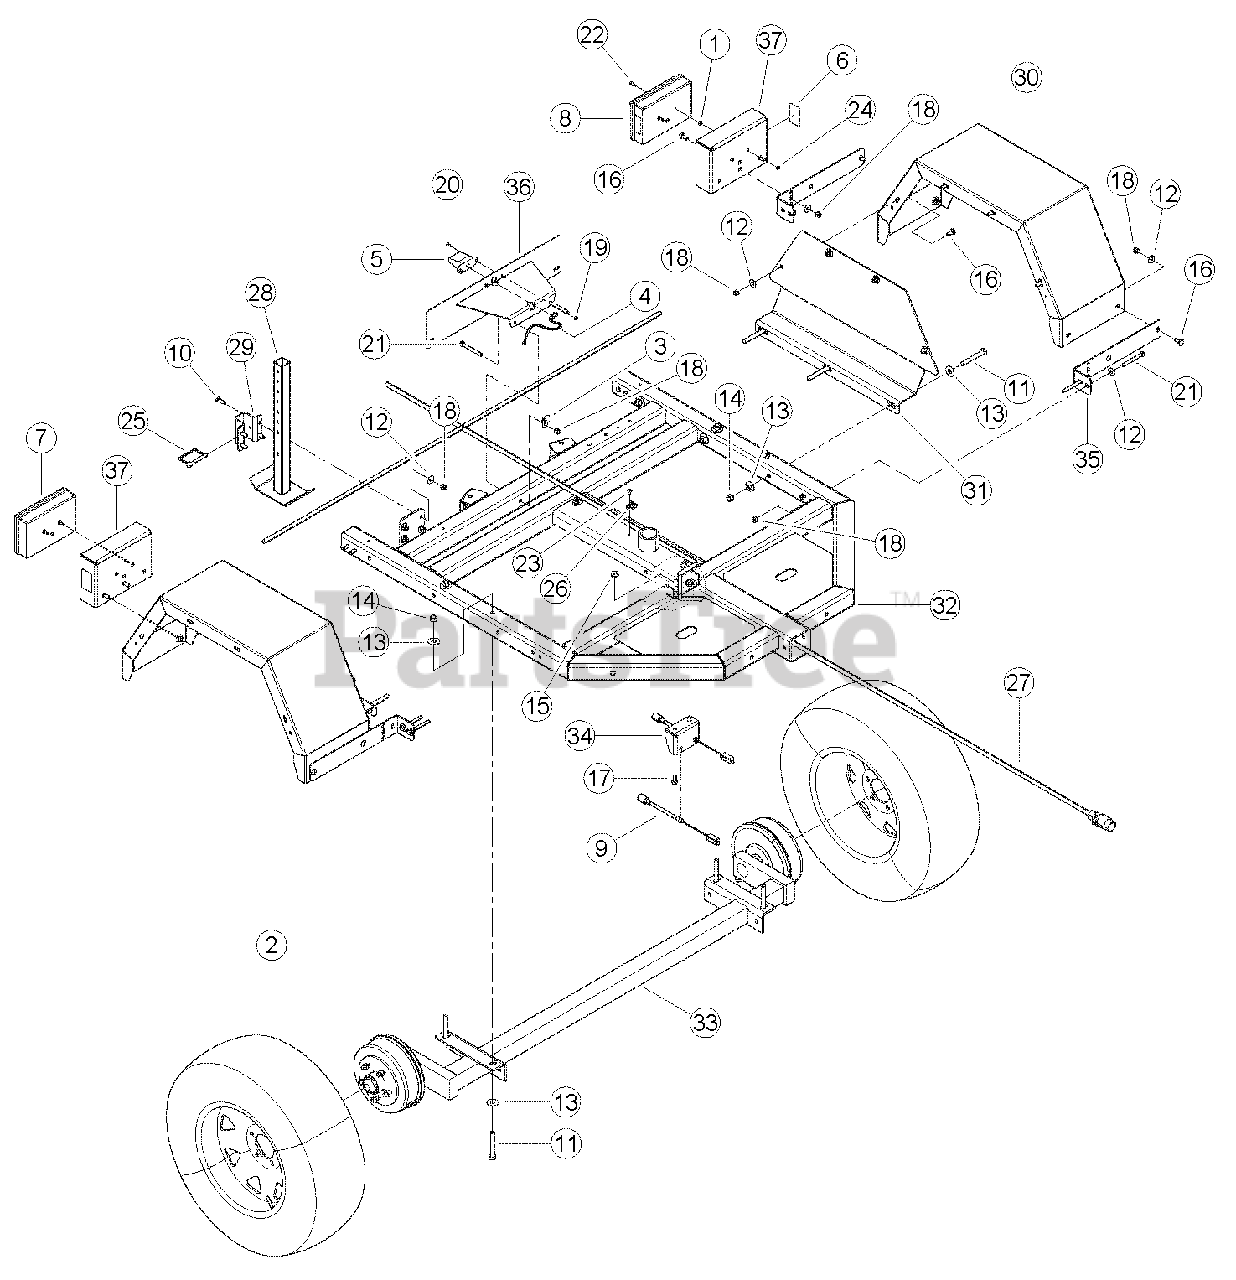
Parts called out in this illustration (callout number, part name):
1	GROMMET, 1/4 X 5/8 RUBBER
2	ASSY, 15 INCH TIRE + WHEEL
3	CLAMP, 9/16" COATED
4	PLUG, 12 VOLT LIGHT
5	LIGHT, LICENSE PLATE
6	REFLECTOR, WIDE ANGLE RED
7	LIGHT, TAIL RH
8	LIGHT, TAIL LH
9	CABLE, BRAKE
10	BOLT, 3/8 X 1 HEX HD GR5 ZP
11	BOLT, 1/2 X 3-1/2 HEX HD GR5 ZP
12	WASHER, 3/8 FLAT ZP
13	WASHER, 1/2 FLAT ZP
14	NUT, 1/2 CENTERLOCK GRB ZP
15	NUT, 7/16 SERR FLANGE NC ZP
16	BOLT, 3/8 X 1 CRG GR5 NC ZP
17	BOLT, 7/16 X 3/4 HHCS GR5 ZP
18	NUT, 3/8 NE NYLOCK ZP
19	NUT, 10/24 NYLOCK TYPE NM, ZP
20	SCREW, MCH 10-24 X 1/2 PAN HD,PH ZP
21	BOLT, 3/8 X 3-1/4 HEX HD GR5 ZP
22	BOLT, 10-24 X 3/4 HHCS GR8 PLAIN
23	RIVET, AL BLIND 1/4 X 3/4 DOME HEAD
24	NUT, #10-24 K-LOCK ZP
25	PIN, 3/8 X 2-3/4 SNAP
26	CLAMP, CABLE MOUNT
27	HARNESS, CHIPPER TRAILER
28	WELDMENT, REAR STABILIZER
29	GUIDE, TRAILER SUPPORT
30	FENDER, CHIPPER
31	BRACKET, FENDER
32	WELDMENT, CHIPPER TRAILER
33	ASSEMBLY, 2500LB TORSION AXLE
34	WELDMENT,CABLE BRACKET
35	ANGLE, FENDER GUSSET
36	WELDMENT, LICENSE PLATE
37	BRACKET, TAIL LIGHT
